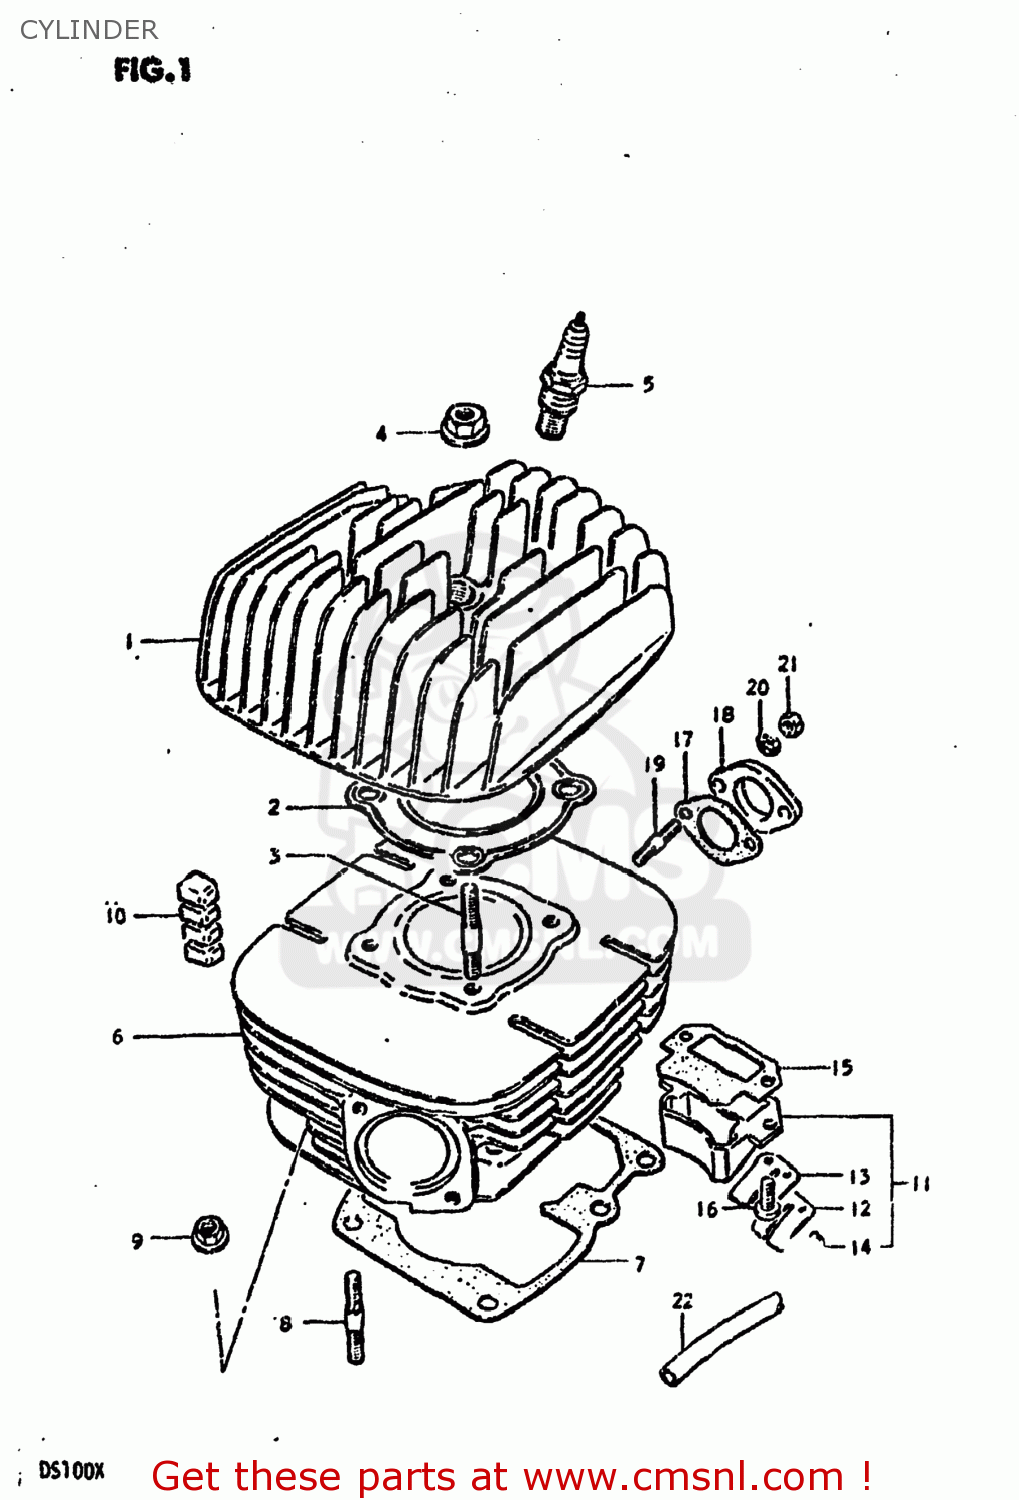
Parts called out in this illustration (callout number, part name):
1	HEAD,CYLINDER
2	GASKET,CYLINDER HEAD (MCA)
3	BOLT,STUD
4	NUT
5	PLUG,SPARK
6	CYLINDER
7	GASKET,CYLINDER (MCA)
8	STUD 8X25
9	NUT
10	PAD,CYLINDER
11	VALVE ASSEMBLY,REED
12	STOPPER,REED VALVE
13	VALVE,REED
14	SCREW,REED VALVE
15	GASKET,REED VALVE (MCA)
16	SCREW
17	GASKET,CARBURETOR (MCA)
18	INSULATOR,CARBURETOR
19	STUD BOLT
20	LOCK WASHER
21	NUT
22	HOSE
